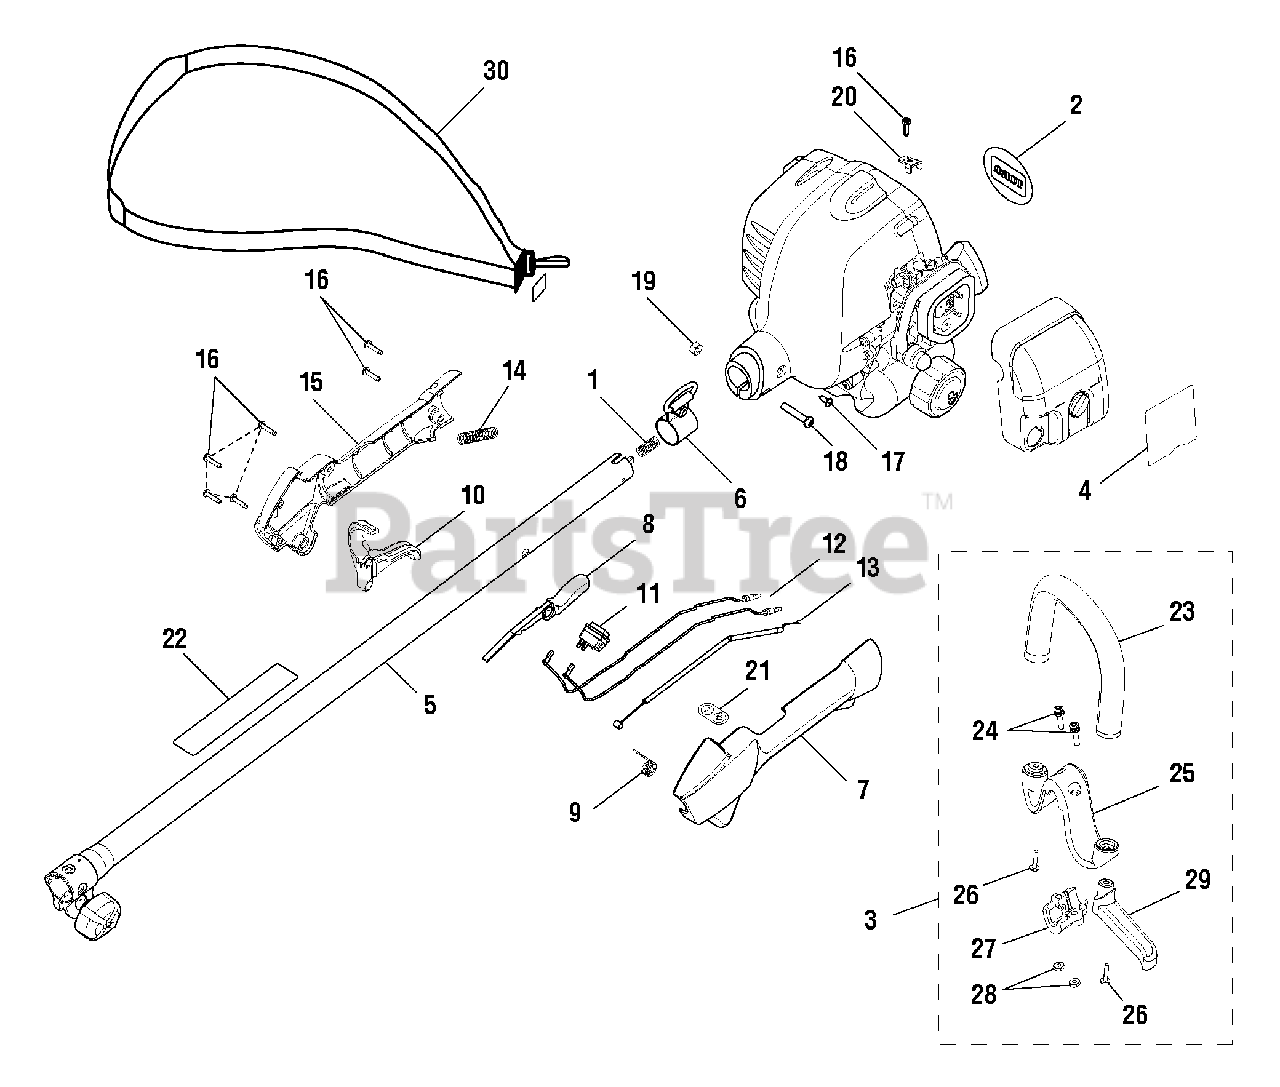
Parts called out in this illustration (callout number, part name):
1	COMPRESSION SPRING
2	LOGO PLATE
3	ASSIST HANDLE W/BARRIER
4	LOWER START LABEL
5	UPPER SHAFT ASSEMBLY
6	HANGER BRACKET .
7	REAR HANDLE SUPPORT
8	LOCK-OFF BUTTON
9	TRIGGER SPRING
11	SWITCH WITH DUST SHIELD
13	CABLE, THROTTLE
14	CORRUGATED TUBE .
15	REAR HANDLE COVER
16	SCREW (M4 X 16 mm)
17	SCREW (#10-14 X 1/2 in. TRI-LOBULAR)
18	SCREW (M6 X 1-30 mm)
19	HEX NUT
20	THROTTLE CABLE CLAMP
21	ON/OFF LABEL .
22	WARNING LABEL
23	ASSIST HANDLE W/GRIP .
24	SCREW (#12-24 X 1 in. SEMS) .
25	M CLAMP .
26	SLOTTED TORX SCREW
28	HEX NUT (12-24)
29	BARRIER BAR
30	HARNESS ASM. W/LABEL .
